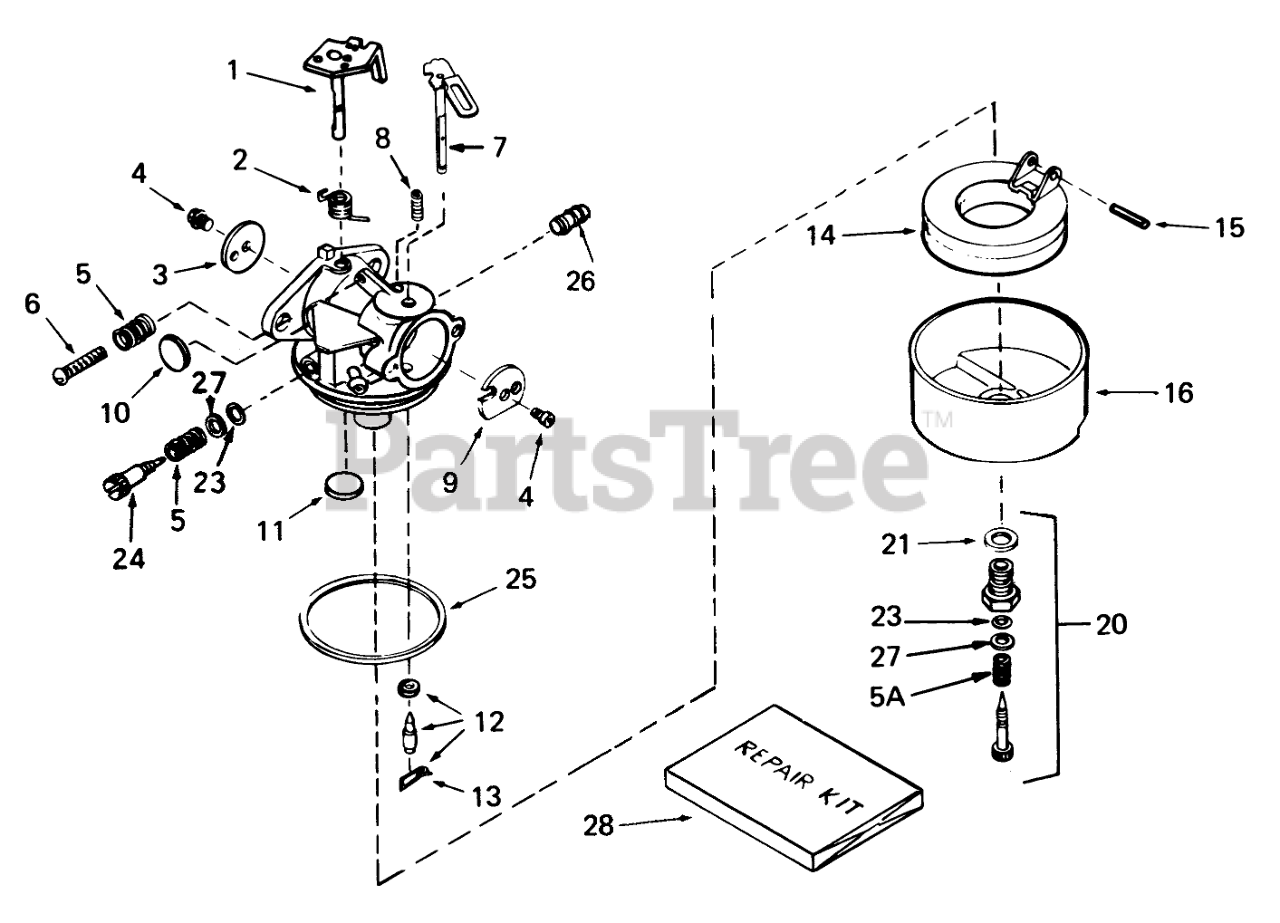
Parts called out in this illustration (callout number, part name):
1	Shaft/Lever-Throttle
2	Spring-Return, Throttle
3	Shutter-Throttle
4	Screw-Shutter
5	Spring-Tension
6	Screw-Throttle Crack Screw / Idle Speed
7	Choke Shaft and Lever ASM
8	Spring-Positioning, Choke
9	Shutter-Choke
10	Plug-Welch, Idle Mixture Well
11	Plug-Welch, Atmospheric Vent
12	Inlet Needle, Seat & Clip Assy. (Incl . Ref. #13)
13	Clip-Spring
14	Float
15	Shaft-Float
16	Bowl-Float (no drain)
20	Adjustment Screw Assy., Main (Incl. Ref. #5A, 21, 23 & 27)
21	Washer-Bowl Nut
23	"O"Ring
24	Screw Main Adjustment
25	O Ring-Bowl, Float
26	Fitting-Fuel
28	Repair Kit
